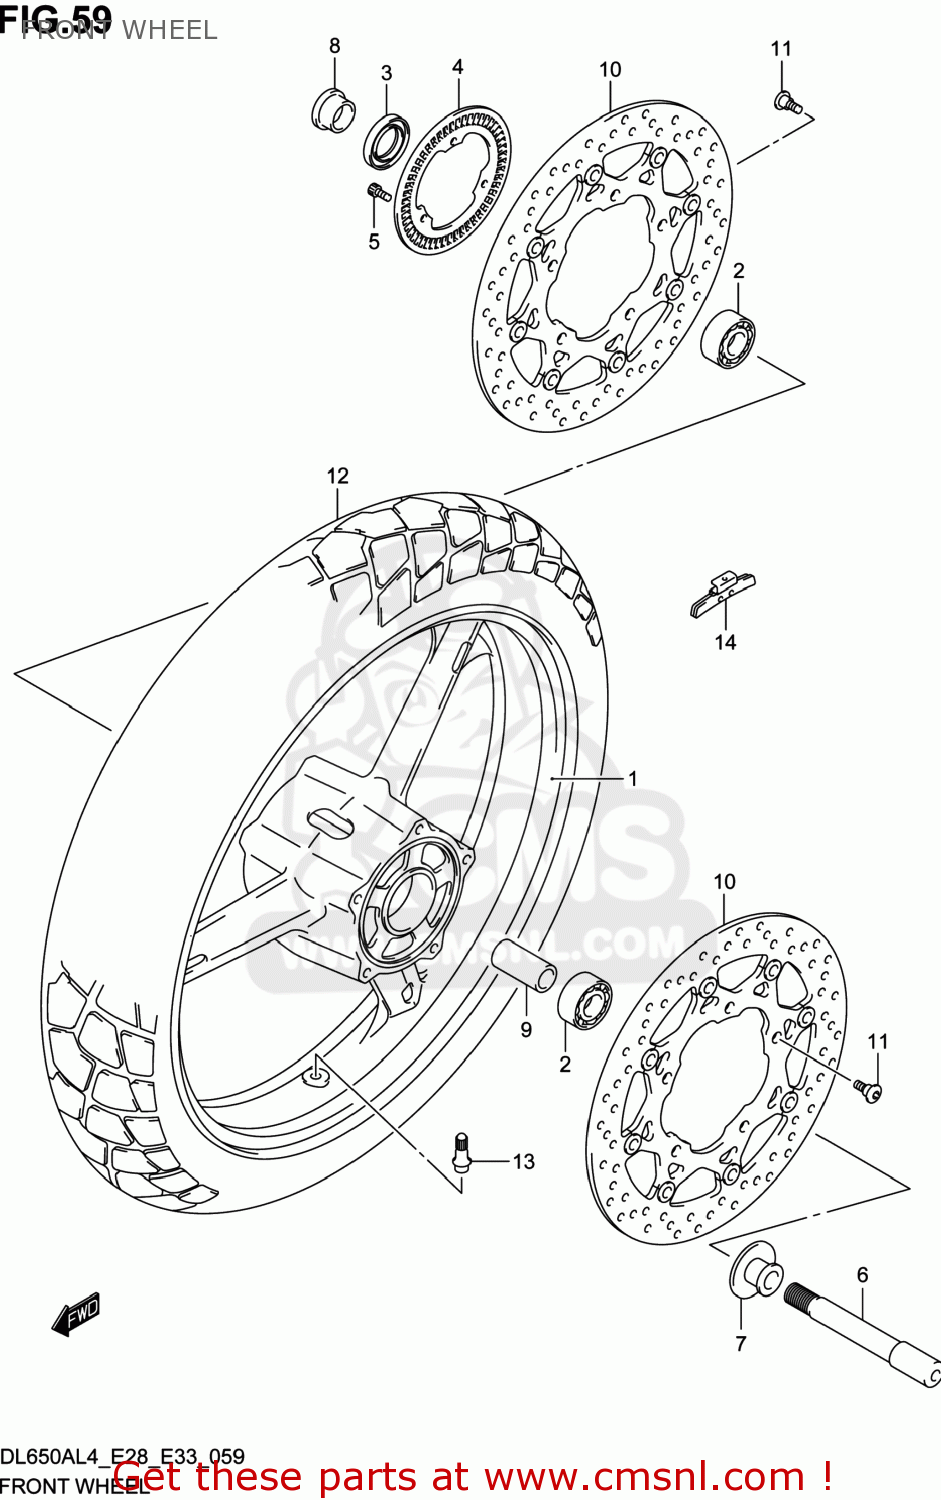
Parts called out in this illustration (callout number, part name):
1	WHEEL,FR(19M/CXMT2.50)
2	BEARING
3	SEAL,OIL(24X40X7)
4	RING,SPEED SENSOR FR(50T)
5	BOLT
6	AXLE,FR
7	SPACER,FR AXLE,L
8	SPACER,FR AXLE
9	SPACER(17.5X25X88)
10	DISC,FR BRAKE
11	BOLT(8X21)
12	TIRE,FRONT,110
13	VALVE ASSY,WHEEL RIM(TR412)
14	WEIGHT,WHEEL BALANCE 10G
